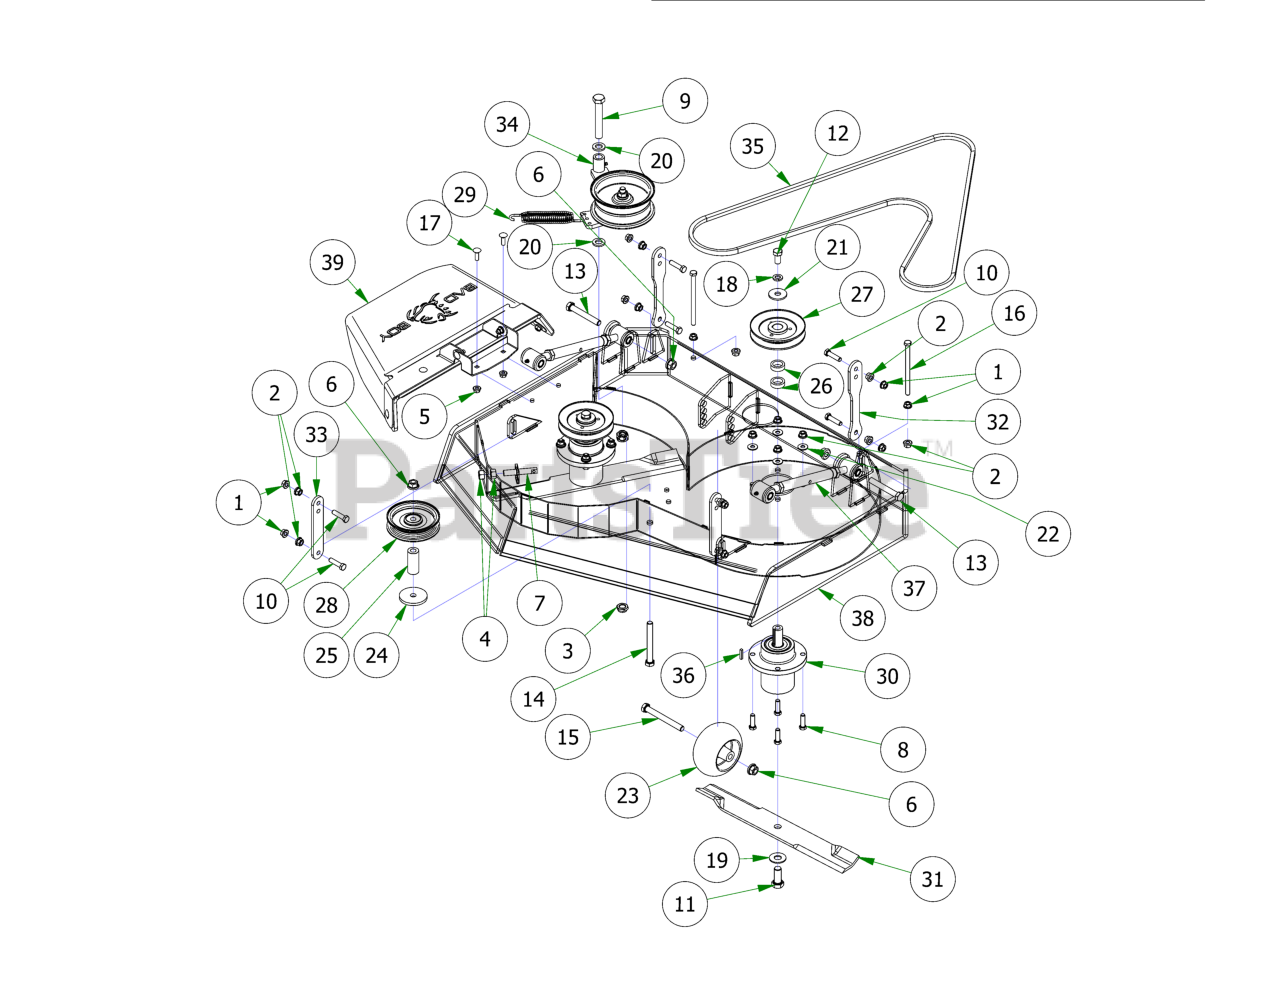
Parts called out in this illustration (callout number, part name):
1	3/8-16 HEX SERRATED FLANGE NUT HARD/ZINC
2	3/8-16 NYLON INSERT FLANGE LOCKNUT (GR.F) ZINC
3	5/8-11 NYLON INSERT JAM LOCKNUT ZINC
4	1/2-13 HEX NUT ZINC
5	5/16-18 NYLON INSERT FLANGE LOCKNUT ZINC
6	1/2-13 NYLON INSERT FLANGE LOCKNUT ZINC
7	All Thread
8	3/8-16 X 1-1/4 HEX CAP SCREW (GR.5) ZINC
9	5/8-11 X 4 HEX CAP SCREW (GR.8) ZINC YELLOW
10	3/8-16 X 1-1/2 HEX CAP SCREW (GR.5) ZINC
11	5/8-18 X 1-1/2 HEX CAP SCREW (GR.8) ZINC YELLOW
12	1/2-20 x 1 Hex Frade 5 ZC
13	1/2-13 X 3-1/2 HEX CAP SCREW (GR.5) ZINC
14	1/2-13 X 4-1/4 HEX CAP SCREW (GR.5) ZINC
15	1/2-13 X 4-1/2 HEX CAP SCREW (GR.5) ZINC
16	3/8-16 X 5-1/2 HEX CAP SCREW (GR.5) ZINC
17	5/16-18 X 1 CARRIAGE BOLT (GR.8) ZINC
18	1/2 SPLIT LOCKWASHER (GR.8) ZINC/YELLOW
19	5/8 USS FLAT WASHER (1-3/4" OD) GR.8 ZINC YELLOW
20	.635 ID X 1.120 OD X .140 THICK FLAT WASHER NYLON
21	1/2 BELLEVILLE WASHER (1-5/8 OD X .140 THK) ZINC
22	5/16 USS FLAT WASHER (7/8 OD) ZINC
23	2019 Deck Wheel
24	MZ Deck Idler Spacer
25	2019 Revolt Stationary Idle Spacer
26	36 Deck Spindle Spacer
27	MZ Deck Pulley
28	5 V Idler Pulley 1/2" Bore
29	2009 Deck/Pump Idler Spring
30	36'' Revolt Spindle Assembly
31	52" Deck Fusion Blade
32	2019 Stand-On Rear Deck Hanger
33	2019 Revolt Front Deck Hanger
34	2020 36" Revolt Deck Idler Assembly
35	2020 Walk-Behind 36 Deck Belt
36	3/16 X 1 SQ MACHINERY KEY 1018 STL ZINC
37	2018 Maverick Turnbuckle (Top Link)
38	2020 Stand On 36" Sloped Deck Welded Assembly
39	2020 36 Stand On Discharge Assembly
